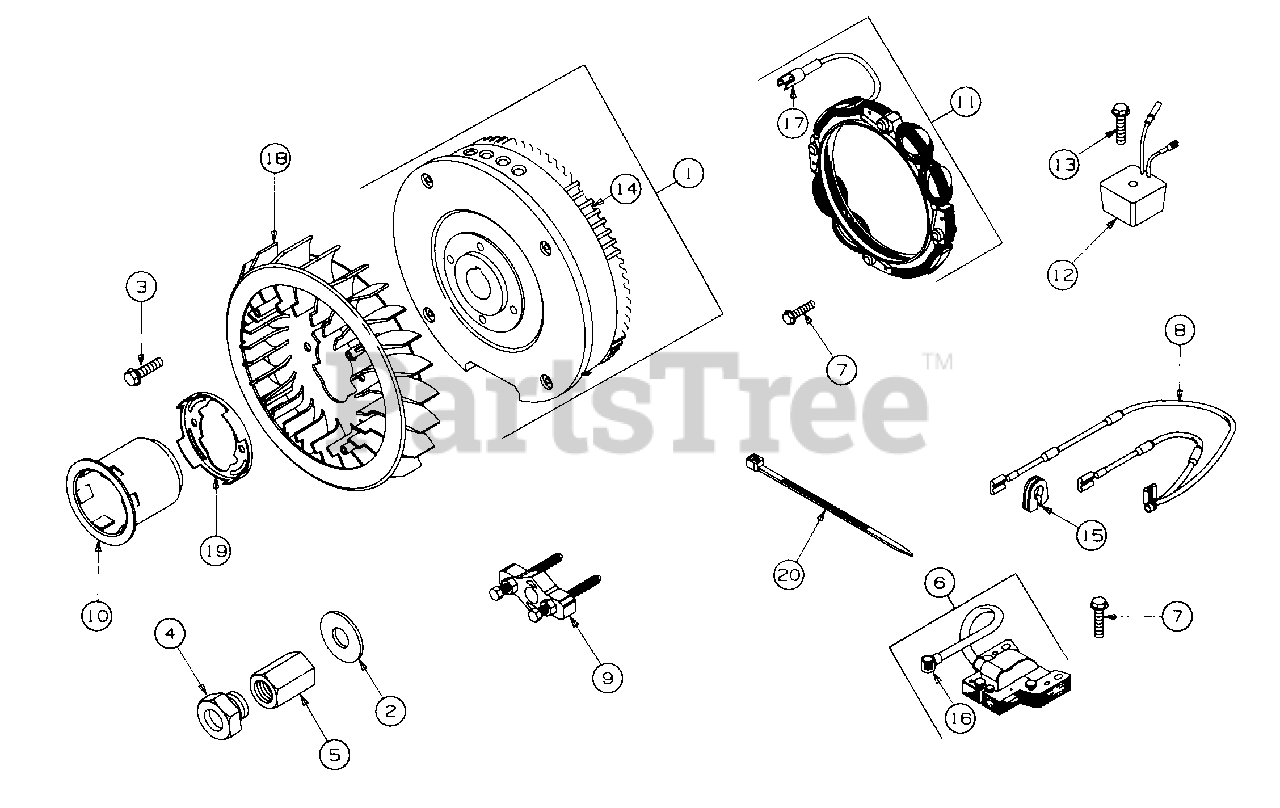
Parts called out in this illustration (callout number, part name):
1	Flywheel, Magneto
2	Washer, Spring
3	Screw, Fan Retainer Mtg
4	Screw, Hex Hd
6	Armature, Magneto
7	Screw, Mounting
8	Wire, Ground
9	Puller, Flywheel
10	Hub, Starter
11	Stator, Alternator
12	Regulator, Alternator
13	Screw, Hex Head
14	Gear, Flywheel Ring
15	Grommet
16	Terminal, Ignition Cable
17	Connector Assy
18	Fan, Flywheel
19	Retainer, Fan
20	Tie, Cable
